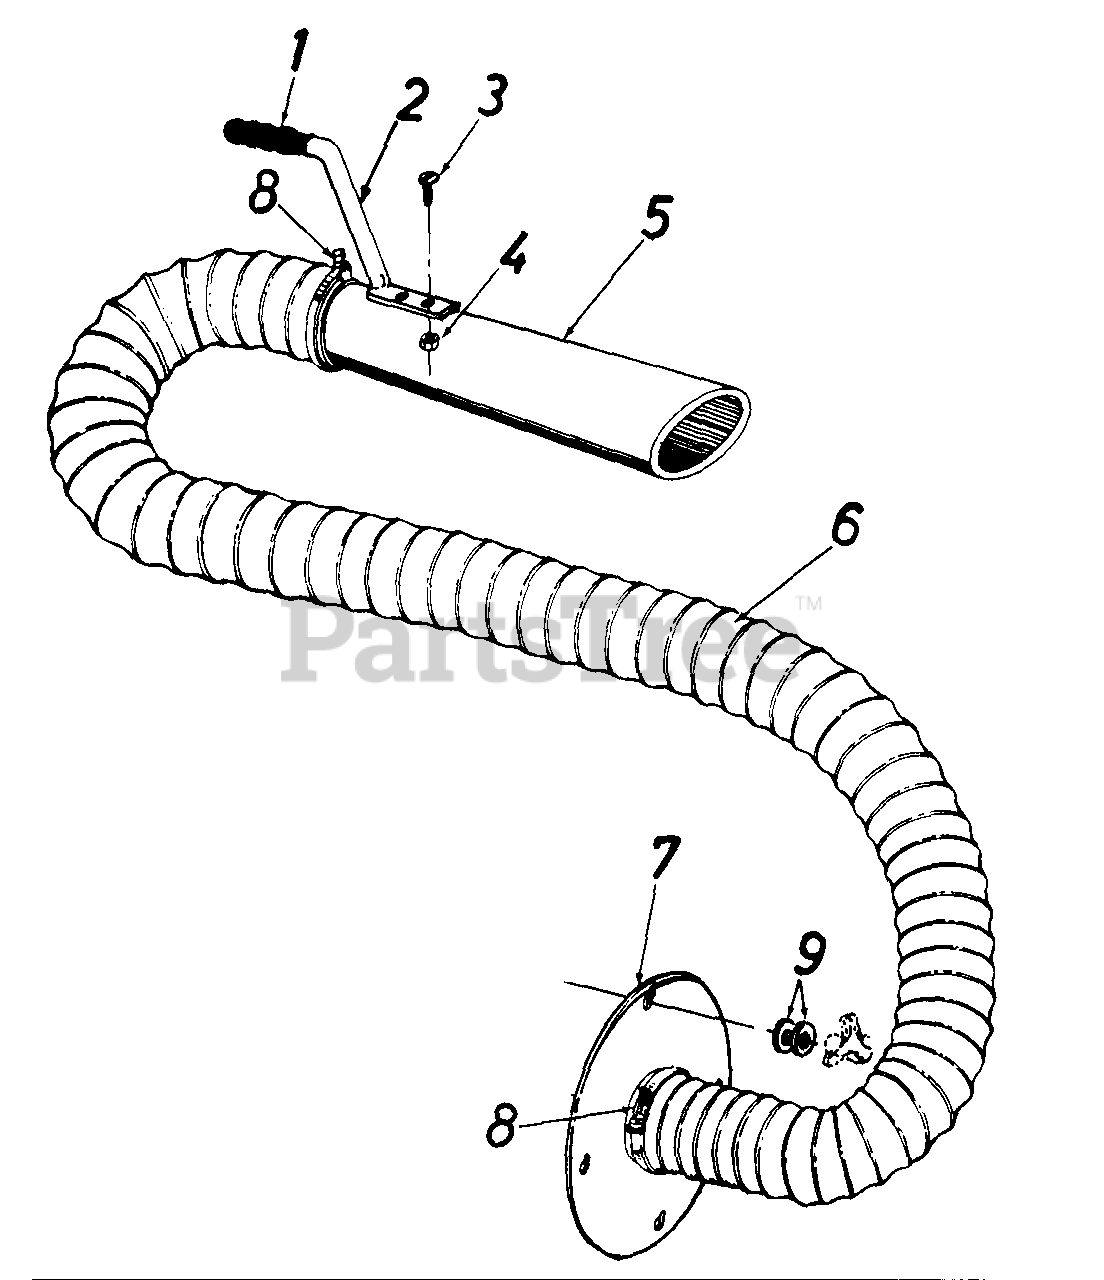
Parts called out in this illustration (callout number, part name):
1	Handle Grip
2	Handle
3	Truss Sems Scr. 10-24 x 1/2" Lg.
4	Hex Nut 10-24 Thd.
5	Hose Nozzle
6	Flexible Hose 4" Dia. x 10' Lg.
9	Flat Washer .34 I.D. x 1.12 O.D.
